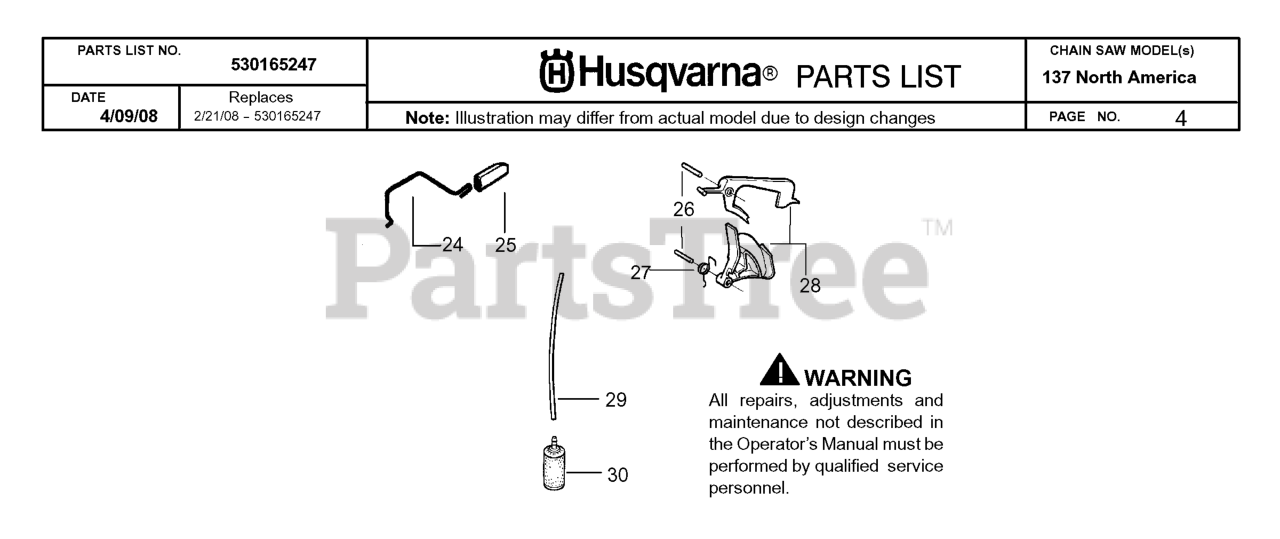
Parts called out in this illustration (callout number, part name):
24	THROTTLE SHAFT 36/41
25	THROTTLE ACTUATOR 36/41
26	PIN,TRIGGER 36/41
27	TRIGGER SPRING 36/41
28	THROTTLE TRIGGER-KIT
29	HOSE. FUEL
30	FUEL PICK-UP
